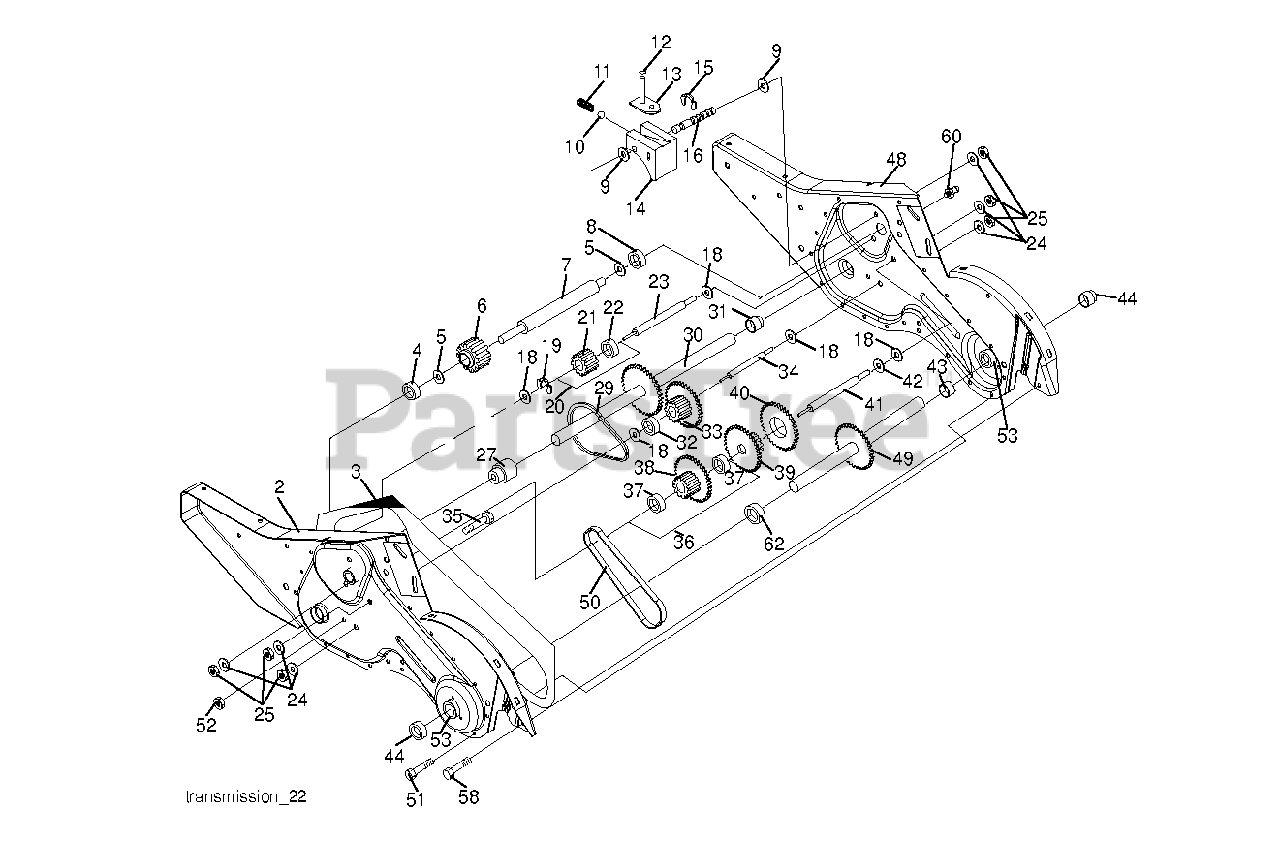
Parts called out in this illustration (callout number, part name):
2	GEARCASE.ASM.CRT.LH.W/BEARING
3	GASKET, GEARCASE
4	NEEDLE BRNG LT
5	THRUST WASHER
6	GEAR.PINION.INPUT
7	SHAFT.INPUT."D".TILLER
8	BEARING TI
9	WASHER, SEAL
10	STEEL BALL KIT
11	SPRING-SHIFT CRT
12	O-RING TI
13	SHIFTING ARM
14	SHIFT FORK TI
15	KLIP RING
16	SHAFT.SHIFTER.TILLER
19	KLIP RING
20	GEAR ASSY CRT
21	GEAR-REV IDLR CRT
22	NEEDLE BEARING TI
23	SHAFT CRT
24	LOCKWASHER
27	BEARING.GROUND.DRIVE
29	CHAIN CRT
30	GROUND SHAFT ASS'Y
31	BEARING, SHAFT RH CRT
32	SPACER TI
33	SPRCKT 8 GEAR CRT
34	SHAFT.SECONDARY.REDUCTION.CRT
35	SCRW WHIZ LOK CRT
36	SPROCKET ASS'Y W/BRG
37	BEARING
38	SPROCKET, TINE
39	GEAR TI
41	SHAFT.REDUCTION.TILLER
42	BRNG RACE T
43	SPACER TI
44	SEAL ASM, OIL
48	GEARCASE.ASM.CRT.RH.W/BEARING
49	SHAFT.ASM.TINE
50	CHAIN.TILLER
51	SCREW
53	BEARING KIT
58	BOLT SHOULDER 1/4-20 UNC X.875
60	FITTING.GREASE.TAPERED
